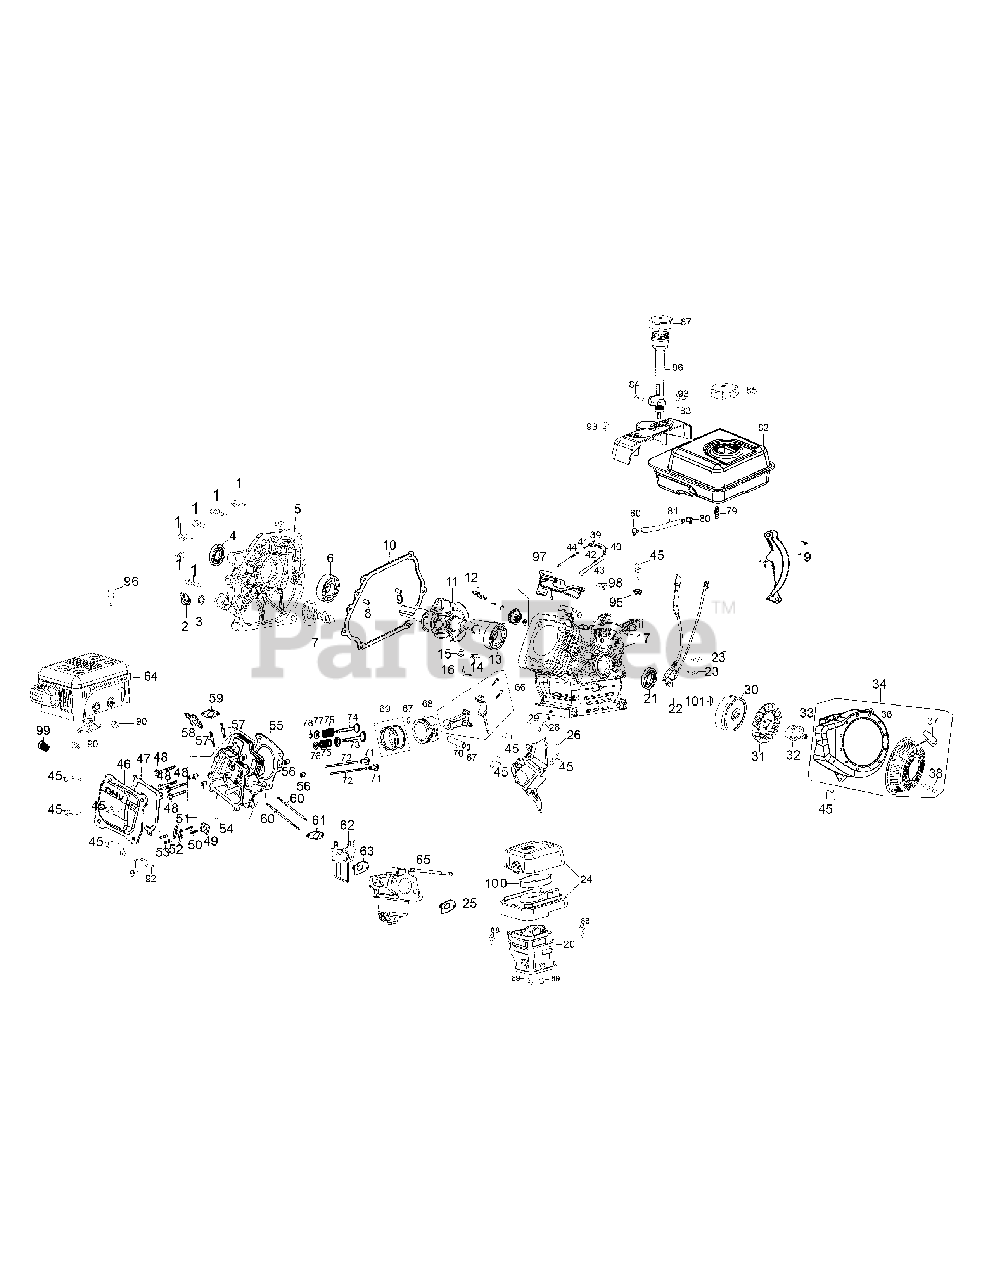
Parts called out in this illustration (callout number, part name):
1	Bolt Flange ×28
2	Dipstick Comp
3	O-Ring
5	Cover Comp Left Crankcase
7	Camshaft Assy.
8	Pin Dowel 7×14
9	Pin Dowel 9×14
10	Gasket Case Cover
11	Crankshaft Comp
12	Governor Gear Kit
14	Pin Lock
14	Locking Pin
15	O-Ring
16	Governor Arm
17	Crankcase Comp.
18	Flywheel Baffle
19	Flange Bolt
20	Intake Heatening Pipe Seat
22	Ignition Coil
23	Flange Bolt
24	Air Cleaner Housing Assembly
25	Packing
26	Air Baffle
28	Bolt Drain Plug
28	Drain Plug
29	Washer.10×16×1.5
31	Cooling Fan
32	Starter Cup
33	Flywheel Nut
36	Fan Housing Cover
37	Recoil Starter Assembly
39	Nut
40	Governor Arm
42	Throttle Return Spring
43	Governor Rod
44	Governor Return Spring
45	Bolt Flange 6×14
46	Cover Comp Head
47	Gasket Cover Head
47	Gasket, Cover Head
48	Bolt Flange 8×50
49	Plate Push Rod Guide
50	Bolt Pivot
50	Pivot Bolt
51	Arm Valve Rocker
52	Adjusting Nut ,Valve
52	Valve Adjusting Nut
53	Nutt Pivot Locking
53	Pivot Locking Nut
55	Gasket, Cylinder Head
55	Gasket Cylinder Head
56	Dowel Pin
57	Muffler Stud Assembly
58	Spark Plug
59	Packing
61	Packing,Insulator
62	Packing,Insulator
63	Packing
64	Muffler Complete
65	Carburetor Assembly
66	Connecting Rod Comp
68	Piston
69	Ring Set Comp,Piston
70	Pin Piston
71	Lifter Valve
72	Push Rod Kit
73	Valve Inlet
74	Valve Exhaust
75	Spring Valve
76	Intake Valve Spring Seat
77	Exhaust Valve Spring Seat
78	Adjuster Ex. Valve
79	Fuel Tank Filter
80	Clip,Tube
81	Tube,Fuel
83	Engine Cover
84	Bolt
85	Cap Comp, Fuel
86	Dipstick Tube
87	Dipstick Assembly
89	Bolt
90	Flange Nut
91	Hose Clamp
92	Breather Hose
93	Panel Bolt
95	Nut
97	Throttle Control Assembly
98	Throttle Control Knob
99	Spark Arrestor
100	Air Cleaner
101	Flywheel Key
